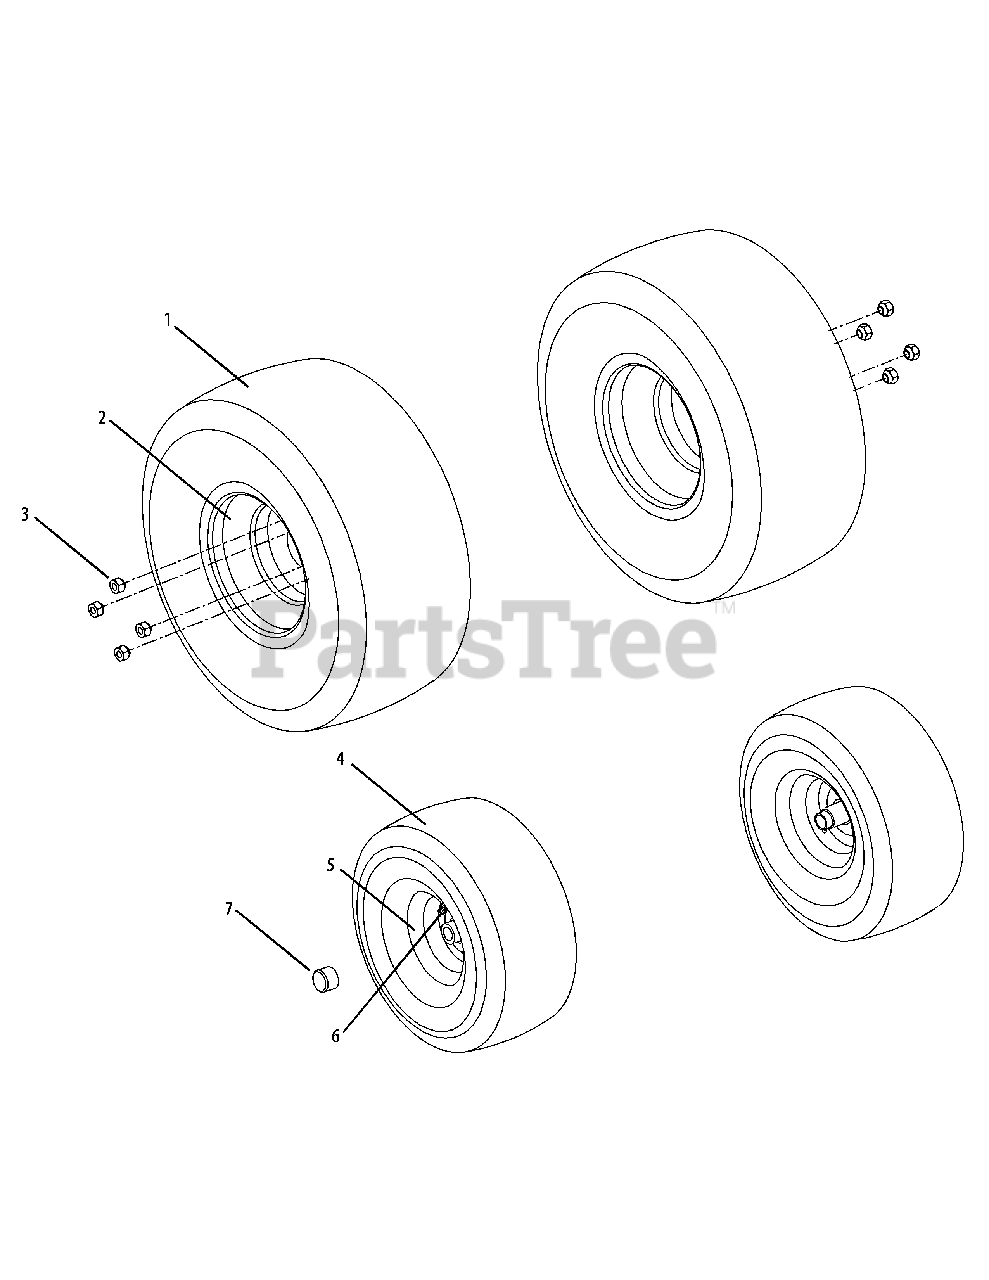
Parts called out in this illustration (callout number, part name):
1	Wheel Ass’y, Complete, 22 x 9.5 x 12
1	Tire, 22 x 9.5 x 12 Square Shoulder
2	Rim Assembly,12.0 x 7.0
3	Lug Nut, 7/16-14
4	Wheel Ass’y, Complete, 15 x 6 x 6
4	Tire, 15 x 6 x 6 Square Shoulder
5	Rim Assembly, 6 x 4.5
6	Valve, Tubeless Air
